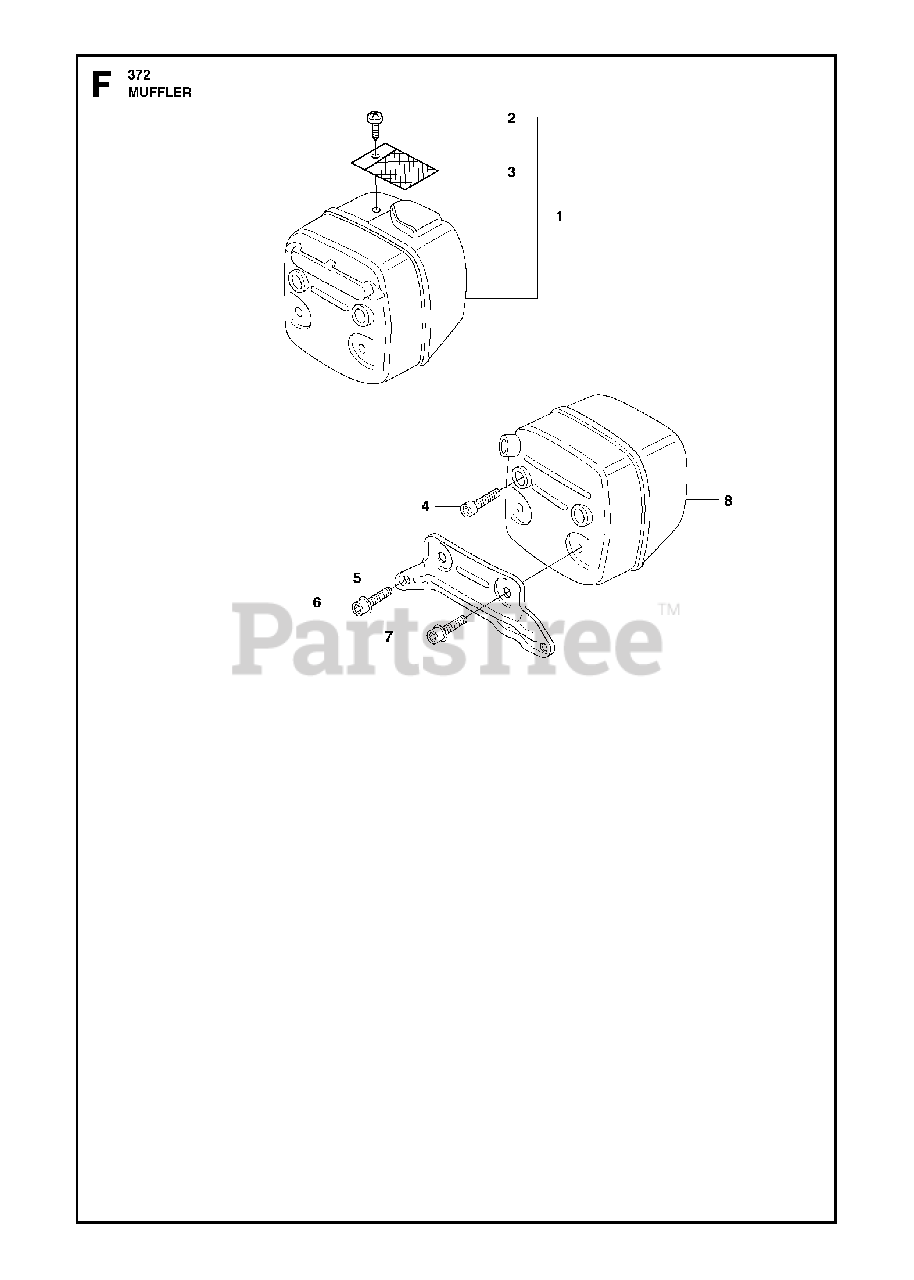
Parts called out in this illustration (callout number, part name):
1	MUFFLER
2	SCREW
3	SCREEN
4	SCREW MC6S 6X20
5	RP SUPPORT
6	SCREW IHSCFM
7	SCREW IHSCFM
8	MUFFLER ASSY
